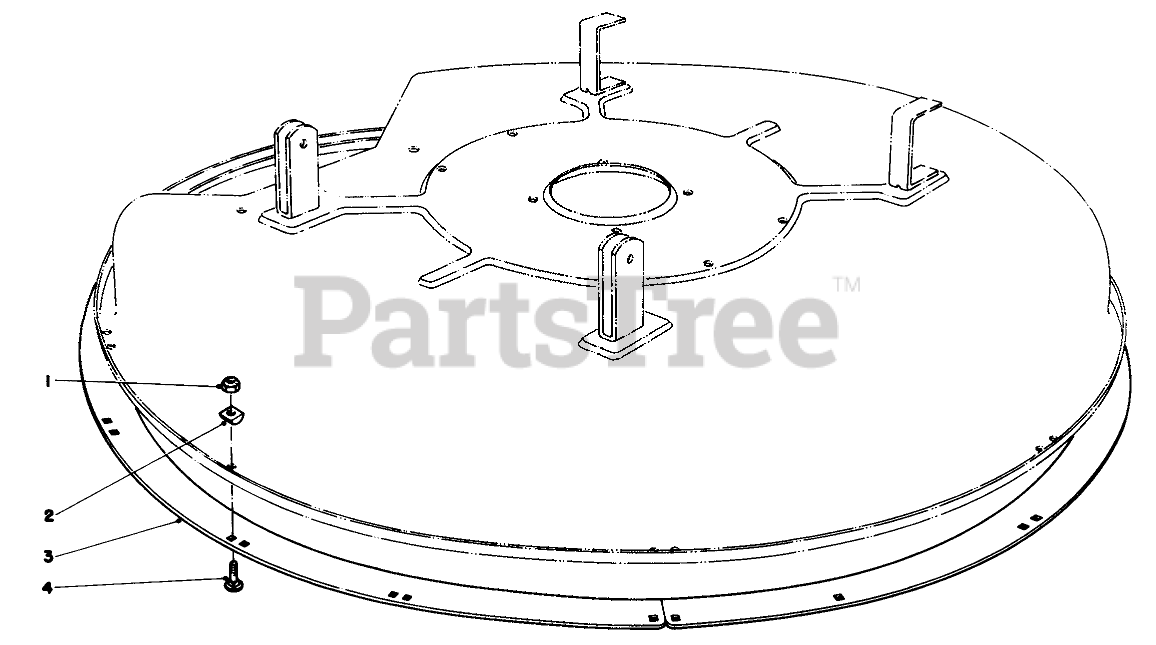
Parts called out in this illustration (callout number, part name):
1	NUT-LOCK, NI
2	DECK RING SPACER
3	DECK RING B
4	BOLT-CARR
